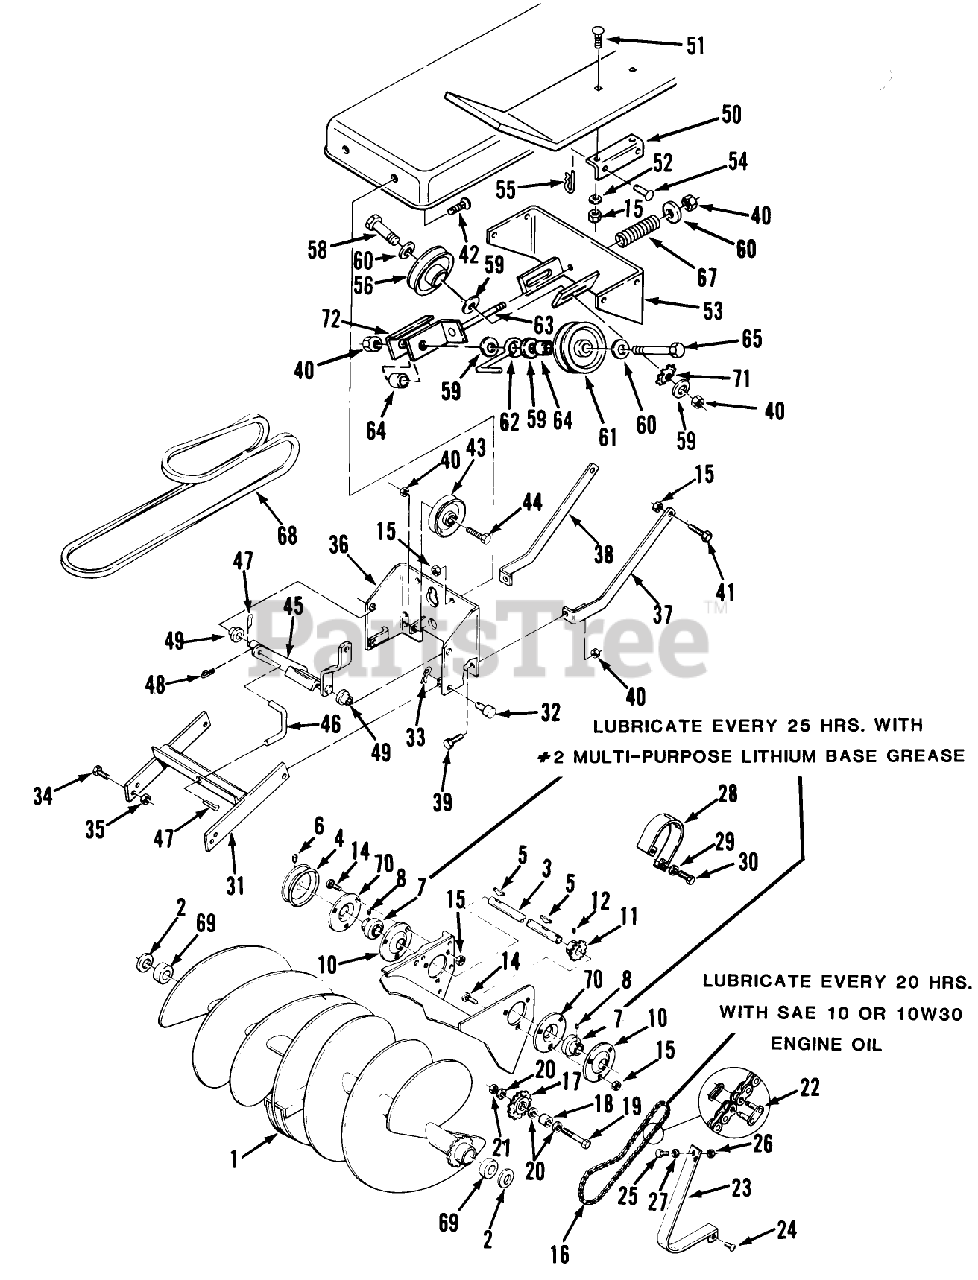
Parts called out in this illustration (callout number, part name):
1	Auger
2	Washer
3	SHAFT
4	PULLEY
5	Key
6	Set Screw
7	BEARING AND COLLAR
8	SET SCREW
10	FLANGE-ZERK RELUBE
11	Sprocket 14T x 40
12	Set Screw
14	Bolt
15	Nut
16	Chain (includes item #22)
17	Idler Sprocket
18	SPACER
19	Bolt 1/2-13 X 2
20	Washer
21	Nut
22	MASTER LINK CHAIN
23	Guard-Outer
24	SCREW
25	H H C S
26	Nut 1/4-20
27	WASHER
28	GUARD-CHAIN R
30	Bolt
31	Mounting Frame
32	PIN
33	Hairpin Cotter
34	BOLT
35	NUT
36	Front Support
37	BRACE-FRAME MT LH R
38	BRACE-FRAME MT RH R
39	BOLT
40	NUT
41	Bolt
42	Bolt-Carriage
43	Flat Idler
44	Bolt
45	ASSY BELLCRANK LI R
46	ROD-FRAME LIFT R
47	Pop Rivet
48	Hairpin
49	BUSHING
50	Quick Attach Plate
51	Bolt
52	WASHER 5/16 SAE
53	Idler Support Bracket
54	PIN
55	Hairpin
56	"V" Pulley
58	Bolt
59	Washer
60	WASHER
61	Idler Pulley
62	RETAINER BELT R
63	ASSY IDLER SLIDE R
64	SPACER
65	Bolt
67	SPRING-COMPRESSION
68	BELT-V 127.0 E L
69	BEARING-BALL
70	Flange
71	WASHER
72	PLATE-BACKUP R
